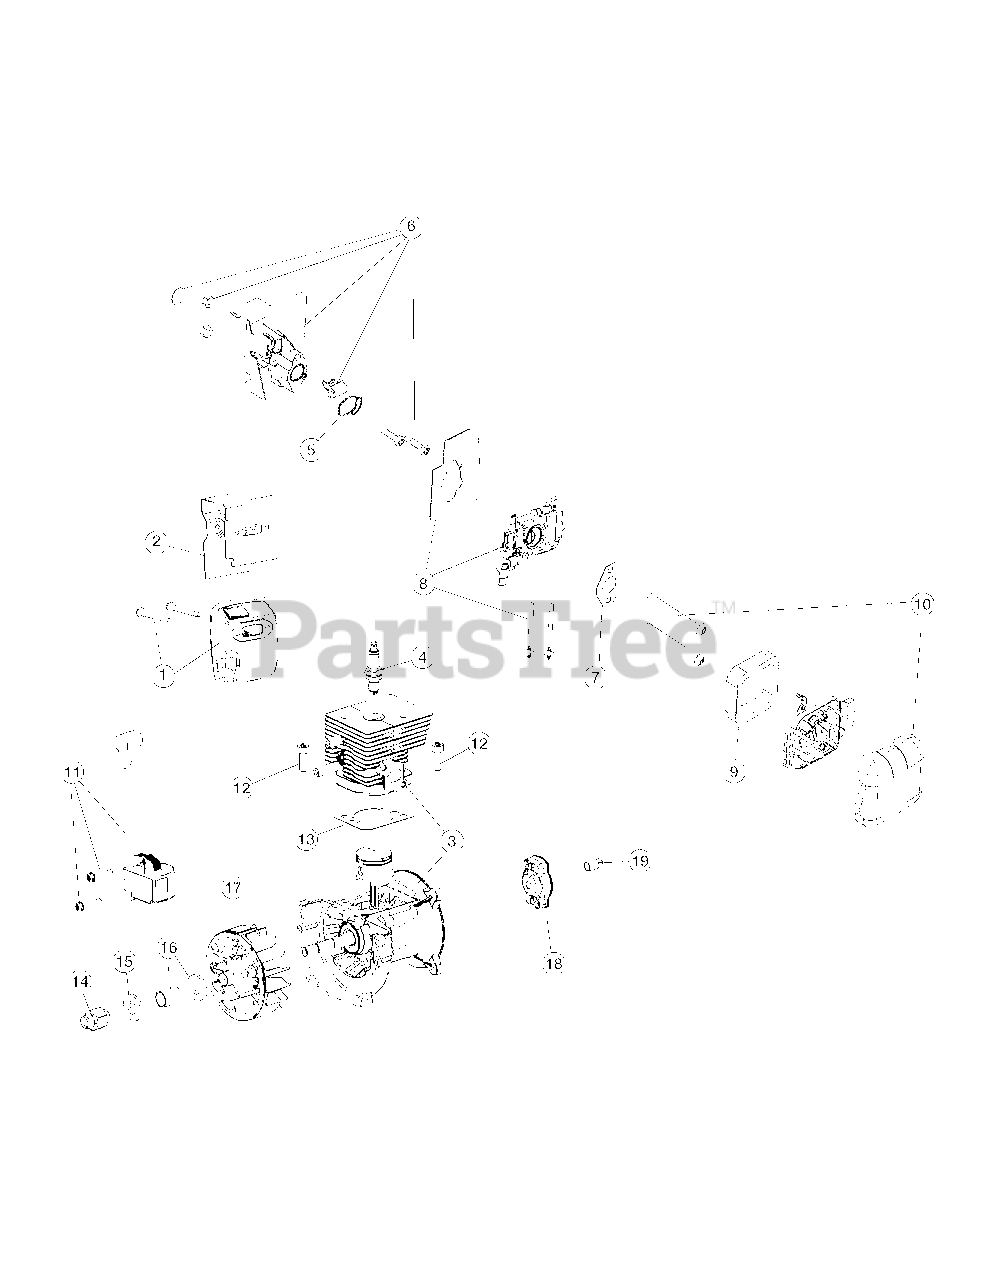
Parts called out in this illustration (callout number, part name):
1	Muffler Assembly (Incl. 2)
2	Muffler Gasket
3	Shortblock Assembly (Incl. 4 & 11-17)
4	Spark Plug
5	Insulator O-Ring
6	Insulator Assembly (Incl. 5)
7	Carburetor Gasket
8	Carburetor Assembly (Incl. 7)
10	Air Cleaner Assembly (Incl. 9)
11	Module Assembly
13	Cylinder Gasket
14	Flywheel Adaptor
15	Washer
17	Flywheel Assembly
18	Pawl Assembly
19	Electric Start Adaptor
